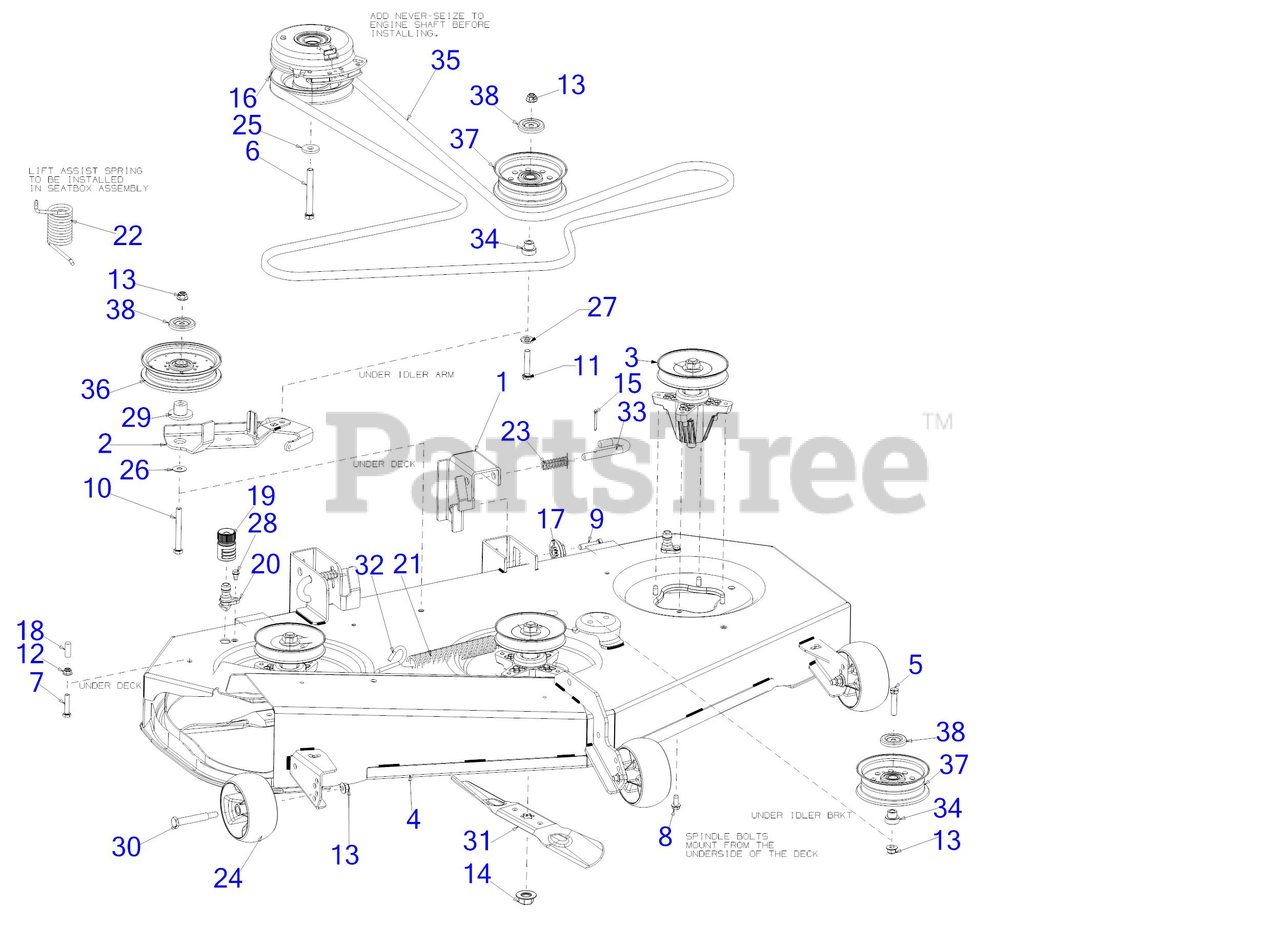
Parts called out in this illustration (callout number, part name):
3	SPINDLE ASSEMBLY
4	50"FAB DECK SHELL
5	HEX SCREW 3/8-16 x 1.75 GR5
6	SCREW 7/16-20 x 3.5 GR5
7	SCREW 5/16-18 x 1.5 LG
8	SCREW 5/16-18 x .750
9	SCREW 3/8-16X1.5 GR5
10	SCREW 3/8-16 x 3.25 GR8
11	SCREW 3/8-16 x 2.0 GR5
12	FLANGE LOCK NUT 5/16-18
15	COTTER PIN-5/32 DIA
16	ELECTRIC PTO CLUTCH
17	DECK ADJUSTMENT GEAR
19	WATER NOZZLE
20	DECK WASH NOZZLE
21	EXTENSION SPRING
22	TORSION SPRING
23	COMPRESSION SPRING
24	DECK WHEEL
25	FLAT WASHER .445 x 1.248 x .170
26	FLAT WASHER
28	SHOULDER SCREW 1/4-20 x .50
29	SHOULDER SPACER
30	SHOULDER BOLT
31	17.27" BLADE (2N1)
32	DECK SPRING HOOK
33	DECK RELEASE PIN
34	SHOULDER SPACER
35	V-BELT B SEC x 143.5 LG
36	FLAT IDLER PULLEY
37	IDLER PULLEY 4.50" DIA
38	IDLER PULLEY CAP
